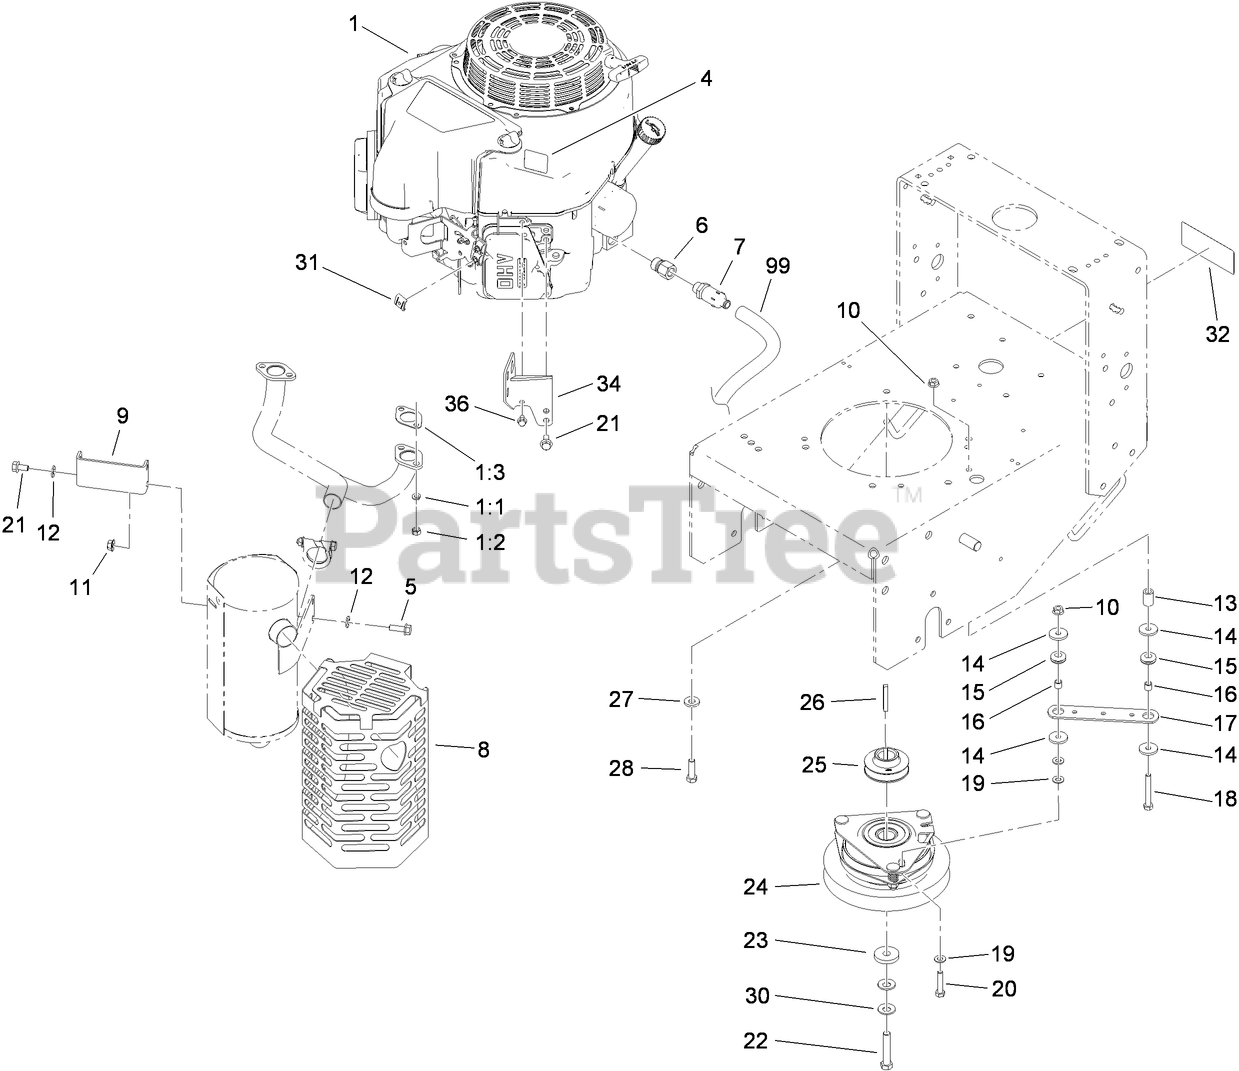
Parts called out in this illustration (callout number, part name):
1:1	WASHER-LOCK
1:3	GASKET-EXHAUST
4	DECAL-WARNING
5	SCREW-HHF
6	Adapter
7	VALVE-DRAIN, OIL
8	SHIELD-MUFFLER
9	BRACKET-SHIELD, MUFFLER
10	NUT-HF
11	NUT-HF, LOCK
12	WASHER-SPRING
13	TUBE-RETAINER
14	WASHER
15	GROMMET
16	SPACER
17	STRAP-CLUTCH, BRAKE
18	SCREW-HH
19	WASHER-PLAIN
20	SCREW-HH
21	SCREW-HHF
22	SCREW-HH
23	WASHER
24	CLUTCH / BRAKE ASM
25	PULLEY-DRIVE
26	KEY-SQUARE
27	WASHER-BELLEVILLE
28	SCREW-HH
30	WASHER-SPRING
31	CLAMP-CABLE
32	DECAL-CAUTION
34	BRACKET-MUFFLER
36	SCREW-HHF
99	HOSE-DRAIN, OIL
